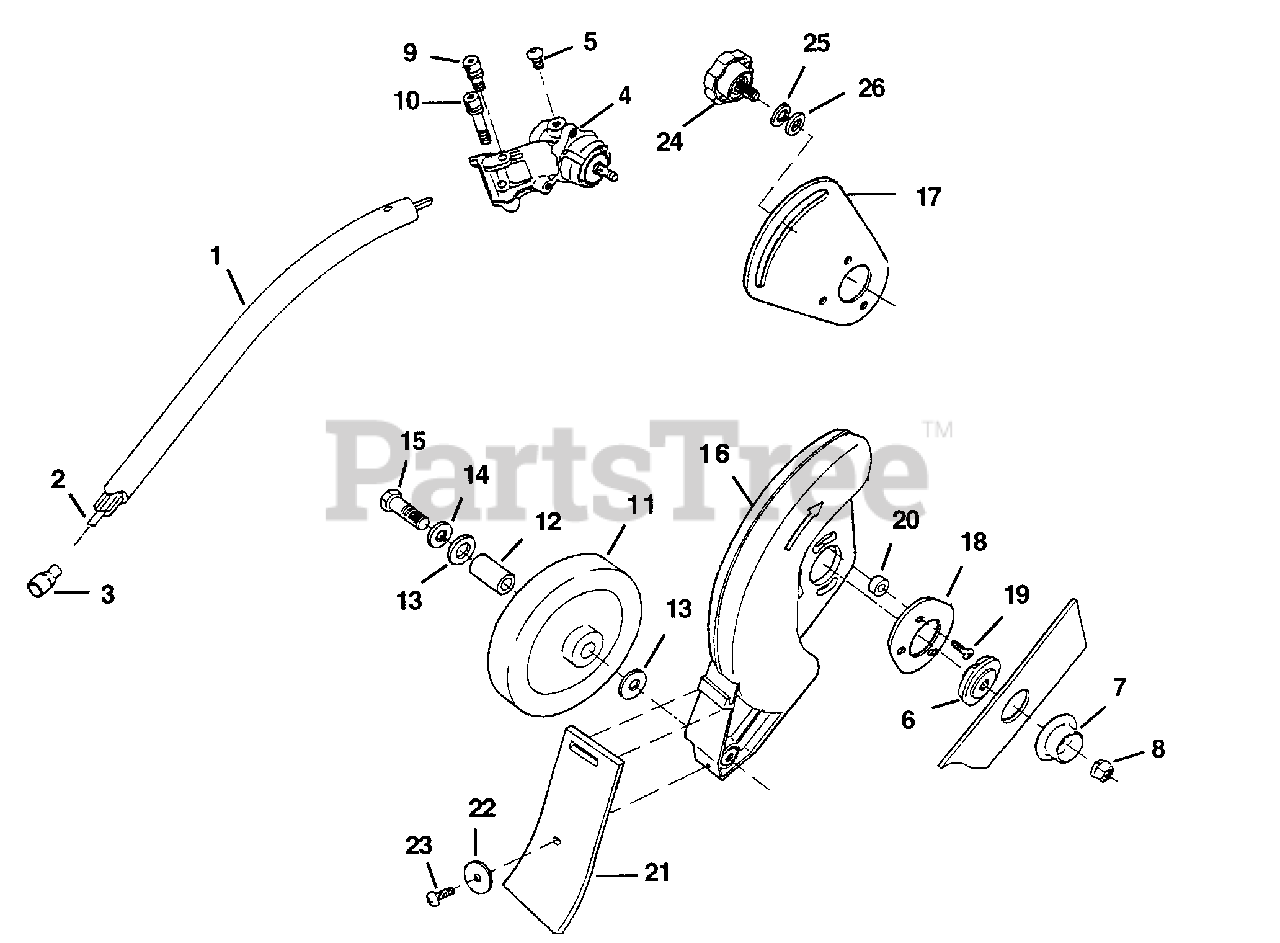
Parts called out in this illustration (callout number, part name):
1	DRIVESHAFT ASSEMBLY
2	SHAFT, Flexible
3	SPACER, Flex Shaft
4	GEAR HEAD
5	BOLT, Oil (M6 x 8)
6	WASHER, Flange
7	WASHER, Cupped
8	NUT(MB)
9	SCREW, Socket Hd (M5 x 25)
10	SCREW, Socket Hd (M5 x 12)
11	WHEEL ASSEMBLY
14	WASHER, Spring
15	BOLT, Hex Hd (M5 x 50)
16	BLADE GUARD ASSEMBLY
17	PLATE, Adjusting
18	PLATE, Mounting
19	SCREW (M5 x 16)
21	DEFLECTOR
23	SCREW, Pan Hd
24	KNOB, Depth Adjust
25	WASHER, Lock
26	WASHER, Flat
